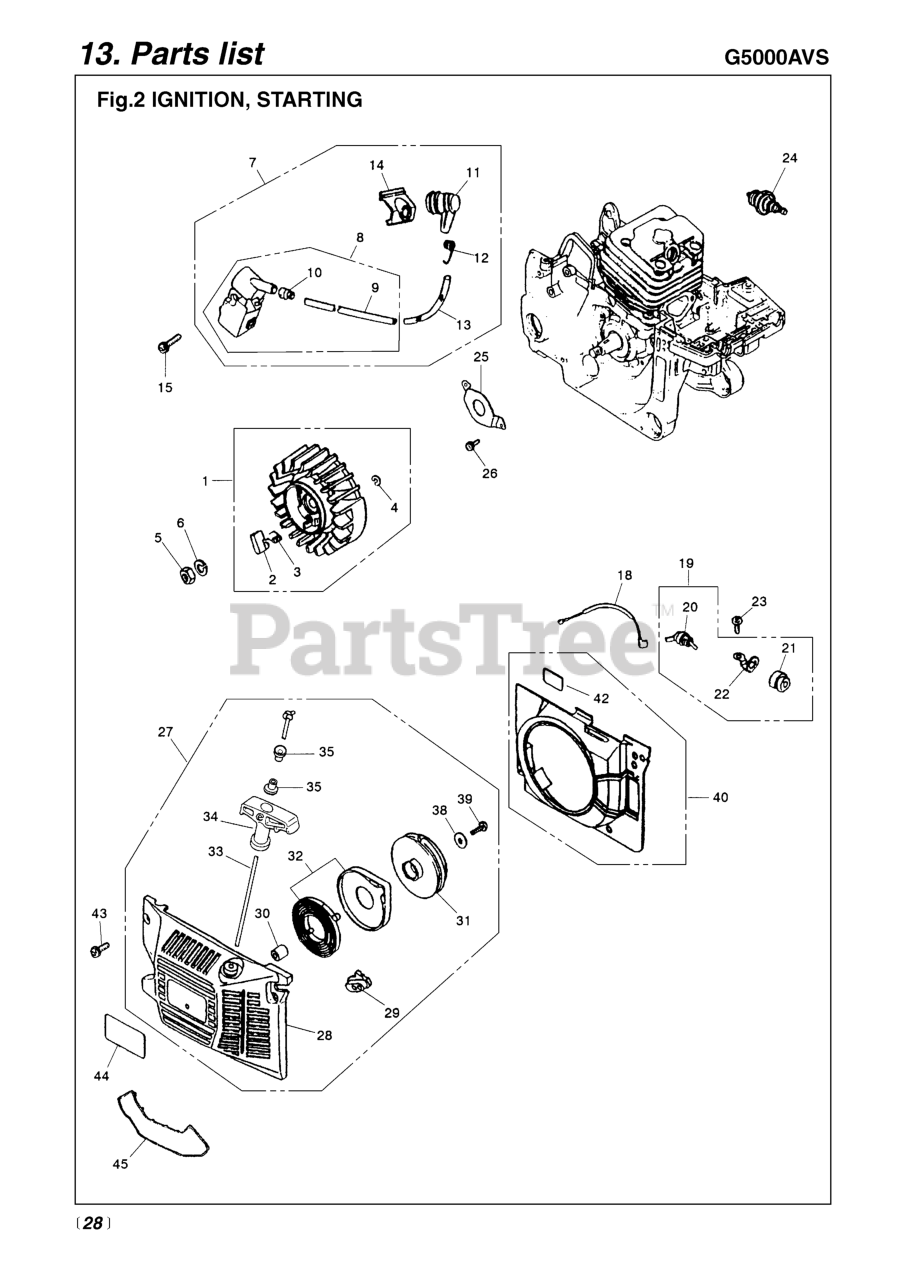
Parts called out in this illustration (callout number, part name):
3	SPRING, RETURN
4	RING, SNAP, M4
5	NUT (RPLS -43230)
6	WASHER, M8 x 20
7	COIL ASSEMBLY
8	COIL COMPLETE
9	CORD, HI TENSION
11	CAP, PLUG
12	SPRING PLUG (RPLS 3310-71320)
19	SWITCH ASSEMBLY
20	SWITCH (REPLACES 2670-71612)
21	COVER, SWITCH
22	PLATE, EARTH
23	SCREW
24	PLUG, SPARK (RPLS 5602-73110)
26	SCREW, M4 X 10
27	STARTER ASSEMBLY
28	CASE, RECOIL (RPLS 2670-75113)
31	REEL (REPLACES -75211)
32	SPRING COMP
33	ROPE (RPLS -75410)
34	KNOB
38	WASHER (USE 181741)
40	COVER COMPLETE
43	SCREW (REPLACES 2616-24320)
44	LABEL, RECOIL
45	SNOW PROTECTOR
